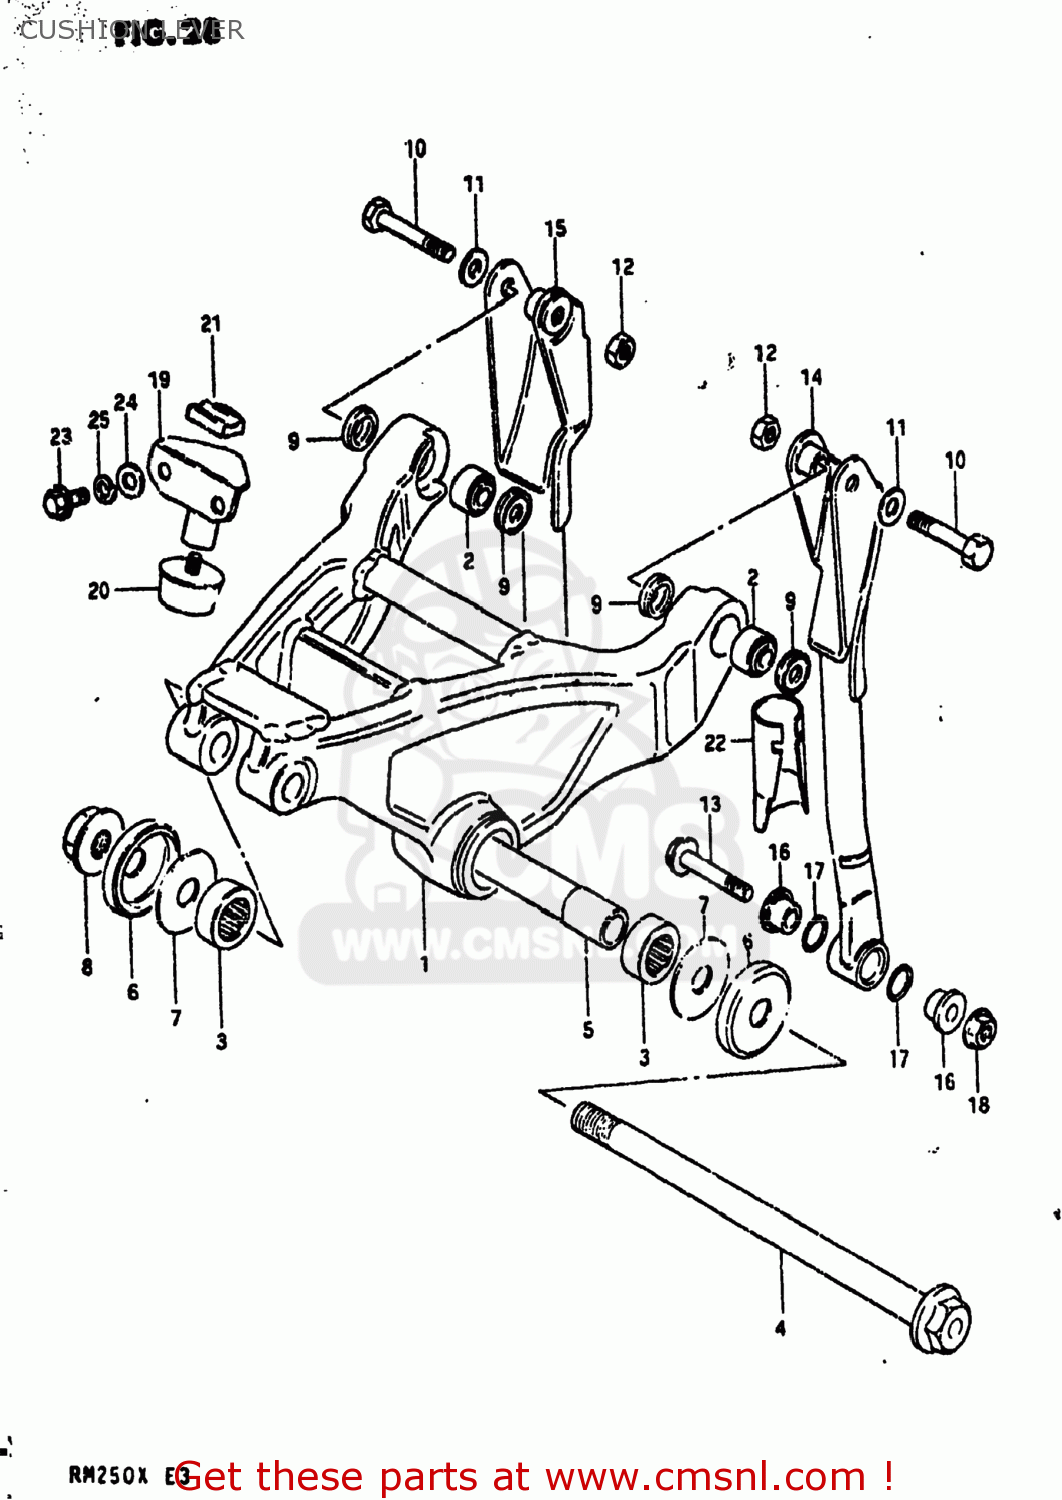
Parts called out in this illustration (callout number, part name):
1	LEVER SET,REAR CUSHION
2	BEARING(8X18X11)
3	BEARING(17X26X20)
4	SHAFT,REAR CUSHION LEVER
5	SPACER,REAR CUSHION LEVER
6	SEAL,REAR CUSHION LEVER
7	WASHER(12X35X2)
8	NUT
9	10
10	BOLT 8X38
11	WASHER
12	NUT
13	BOLT(8X45)
14	ROD,REAR CUSHION LEVER
15	BOLT,REAR CUSHION LEVER
16	SPACER,RR CUSHION ROD LWR
17	O RING(D:1.9,ID:13)
18	NUT
19	STOPPER,TENSION
20	RUBBER,TENSION STOPPER
21	SUPPORT RUB TENS
22	PROTECTOR,REAR CUSHION R
23	BOLT
24	WASHER
25	LOCK WASHER
